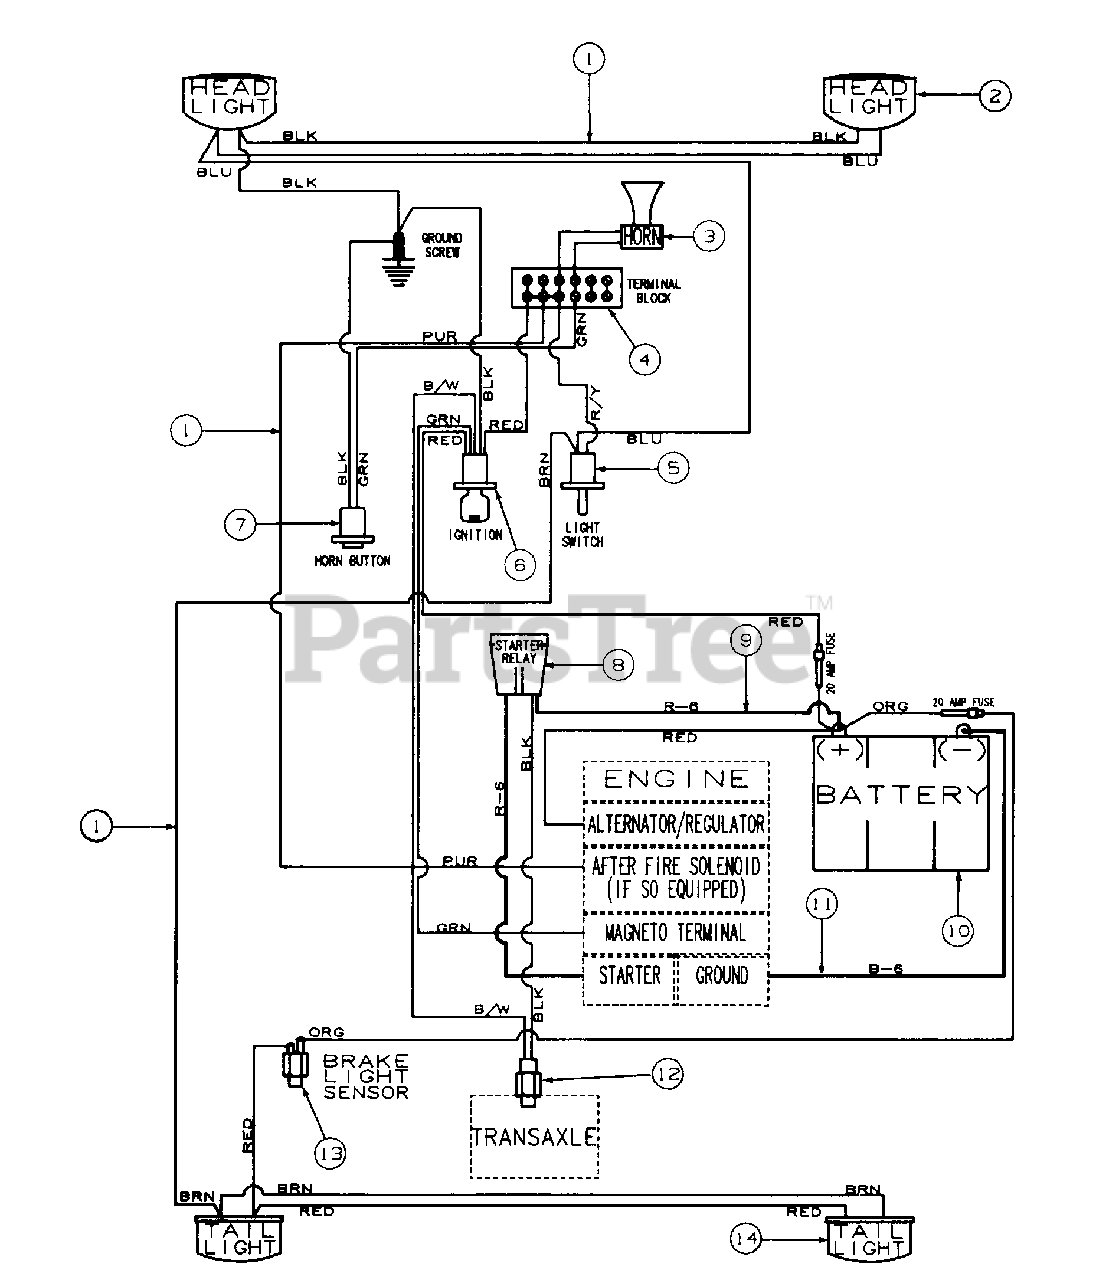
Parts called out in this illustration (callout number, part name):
1	Wiring Harness, Main
2	Headlights w/Hardware
3	Horn, Electric
4	Terminal Block
5	Switch, Push-Pull Light
6	Switch, Ignition
7	Button, Horn
8	Relay, Starter
9	Cable, Battery/Starter, Red
10	Battery
11	Cable, Battery Ground, Black
12	Switch, Neutral Safety
13	Switch, Brake Light
14	Taillight Assy
